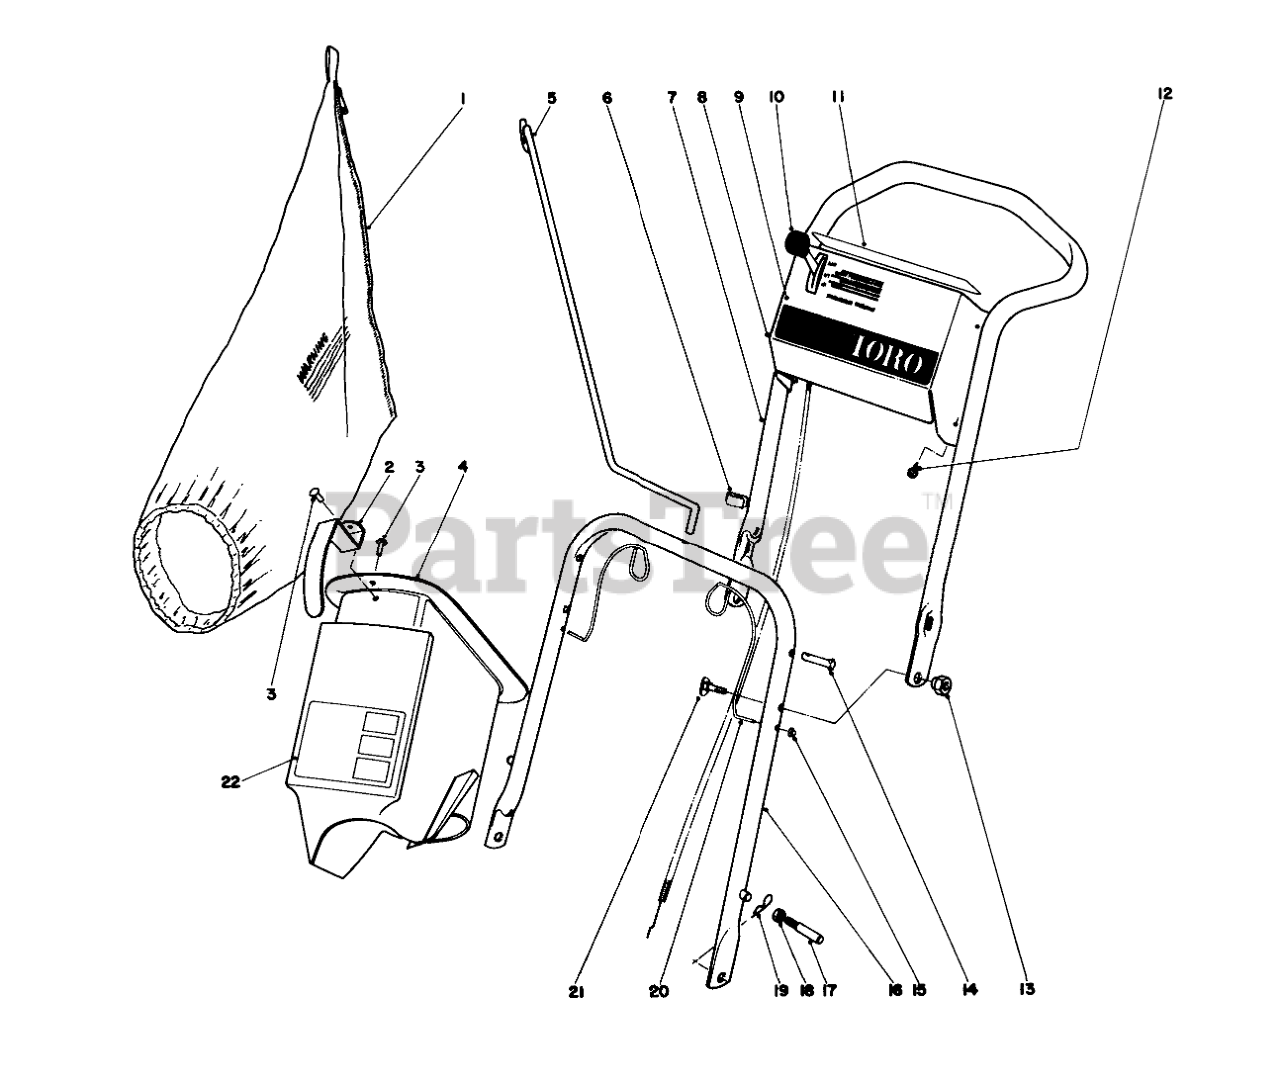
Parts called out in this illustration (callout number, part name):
1	BAG REPLACMNT44-0540
2	HANDLE-GRASS CHUTE
3	RIVET 3/16 X 7/16
4	Grass Chute (Incl. Ref. #2, 3 & 22)
5	Bag Rod
7	Upper Handle
8	Control Plate
9	Decal Control Plate
10	Control Throttle
11	Decal Safety Instructions
12	SCREW-HWHTF
13	Pivot Nut
14	Latch Pin
16	Lower Handle
17	HANDLE PIN
18	Nut
19	PIN-COTTER, HAIR
20	Spring Latch
21	HANDLE SCREW
22	Decal Instructions
